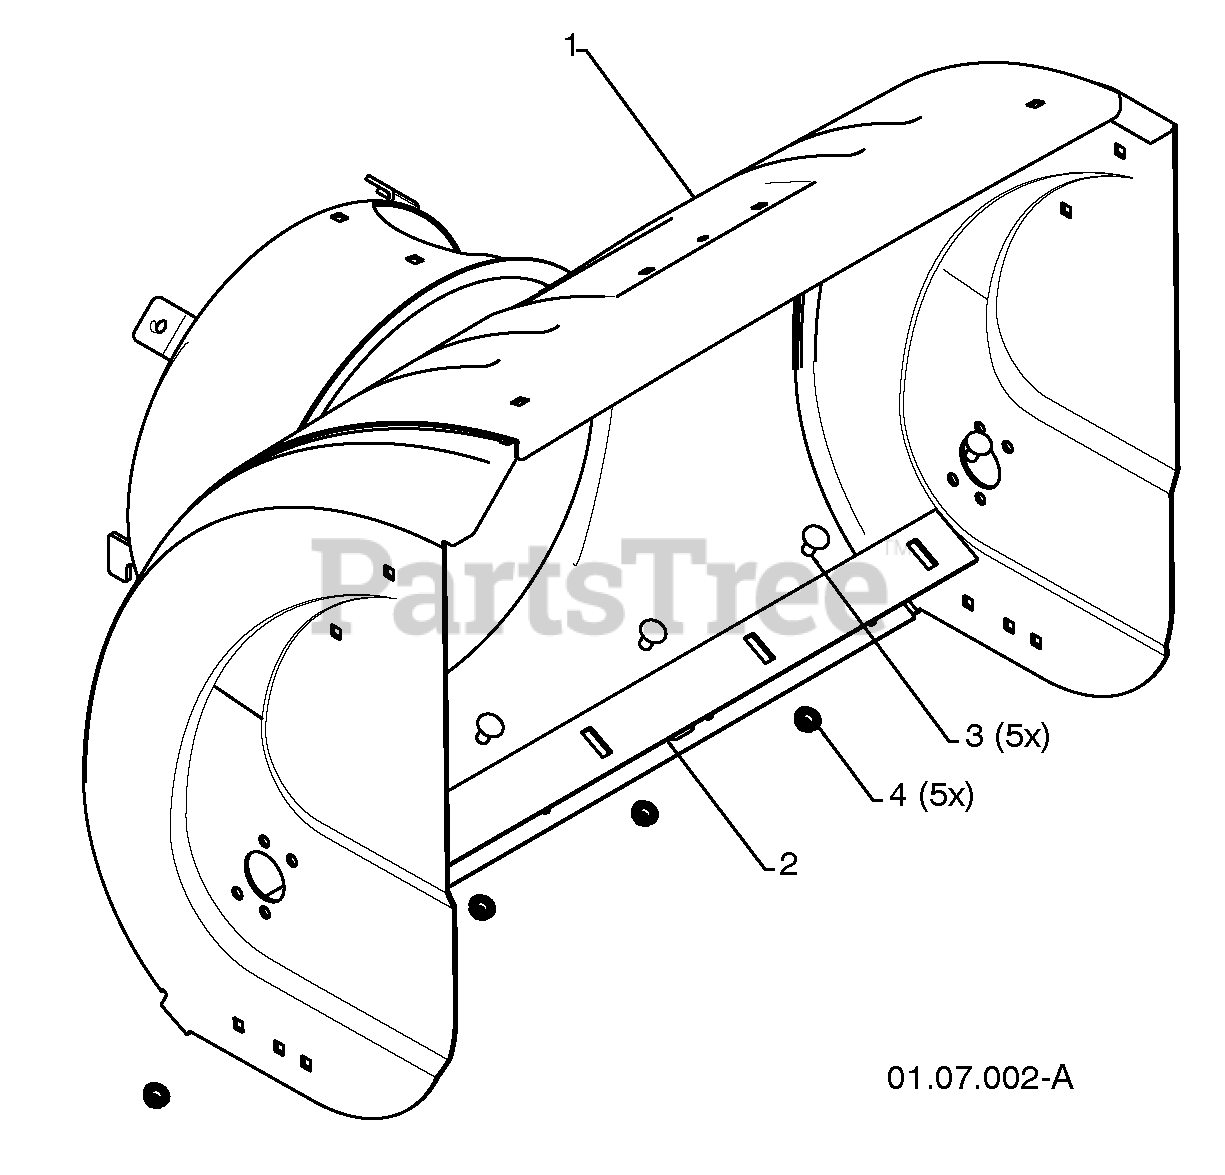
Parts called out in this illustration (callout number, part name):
1	AUGER HOUSING 27
2	SCRAPER BAR
3	CARRIAGE BOLT 5/16-18 X .625
4	NUT 5/16-18
